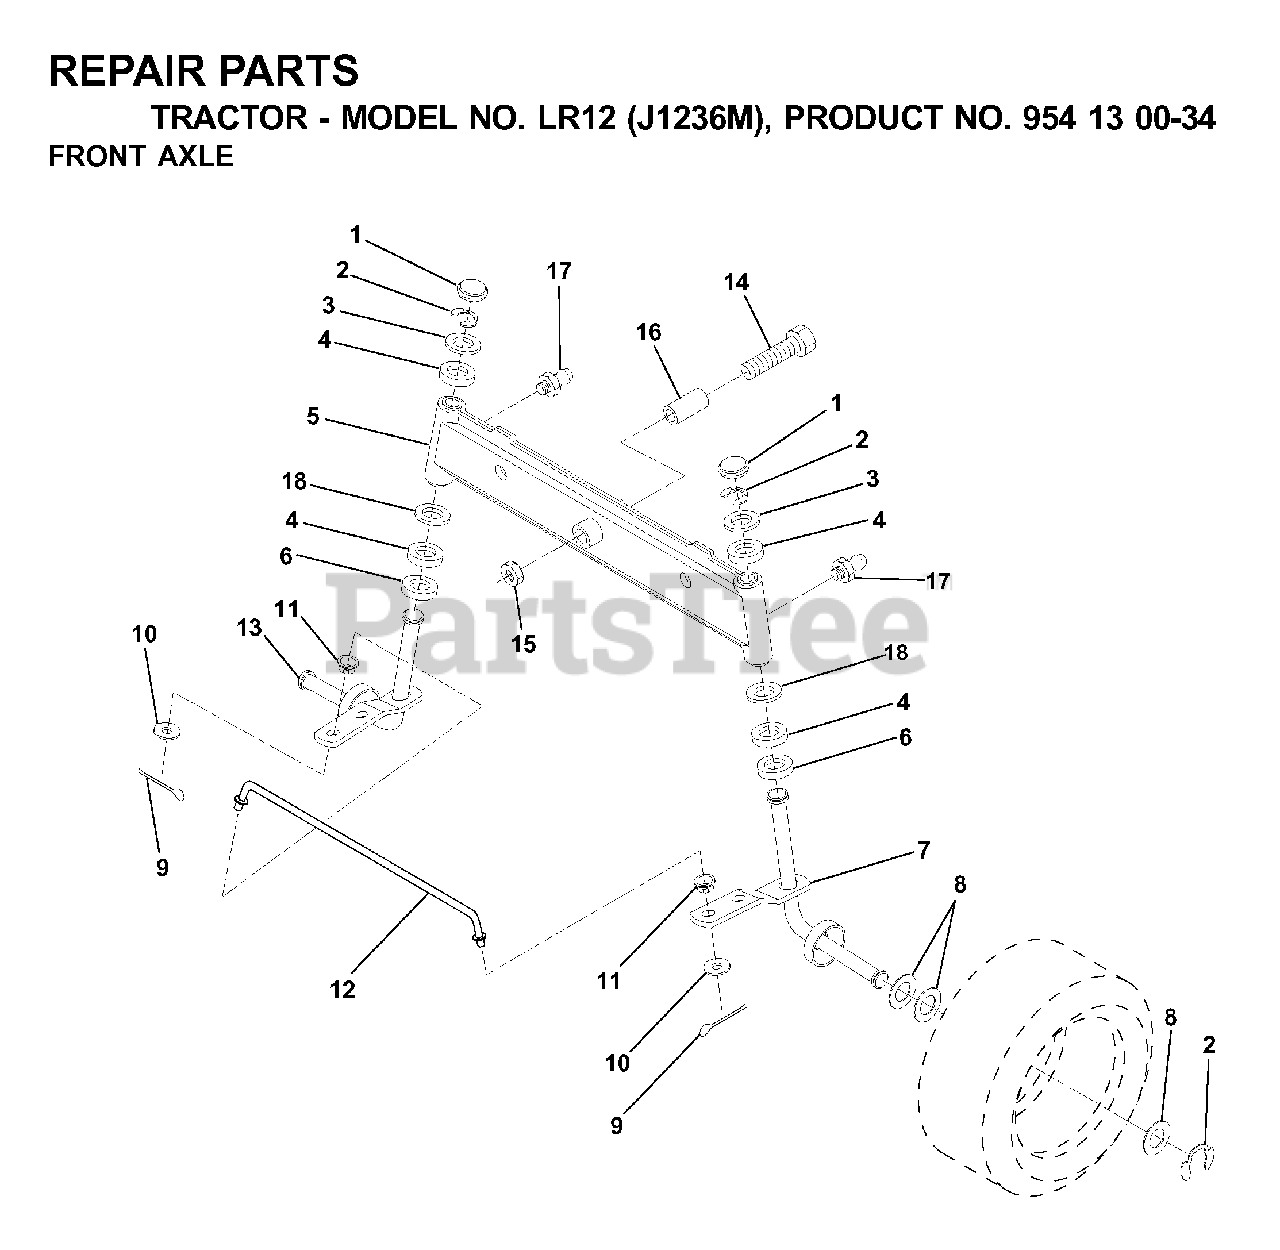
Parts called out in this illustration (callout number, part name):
1	CAP.SPINDLE
2	RING CLIP
4	BRNG T
5	AXLE ASSY
9	COTTER PIN
11	BUSHING.DRAGLINK
12	TIE ROD
13	SPINDLE.ASSEM.LH
14	BOLT.HEX.5/8-11
15	NUT-LOC,FLANGE LT
16	BEARING
17	ZERK M
